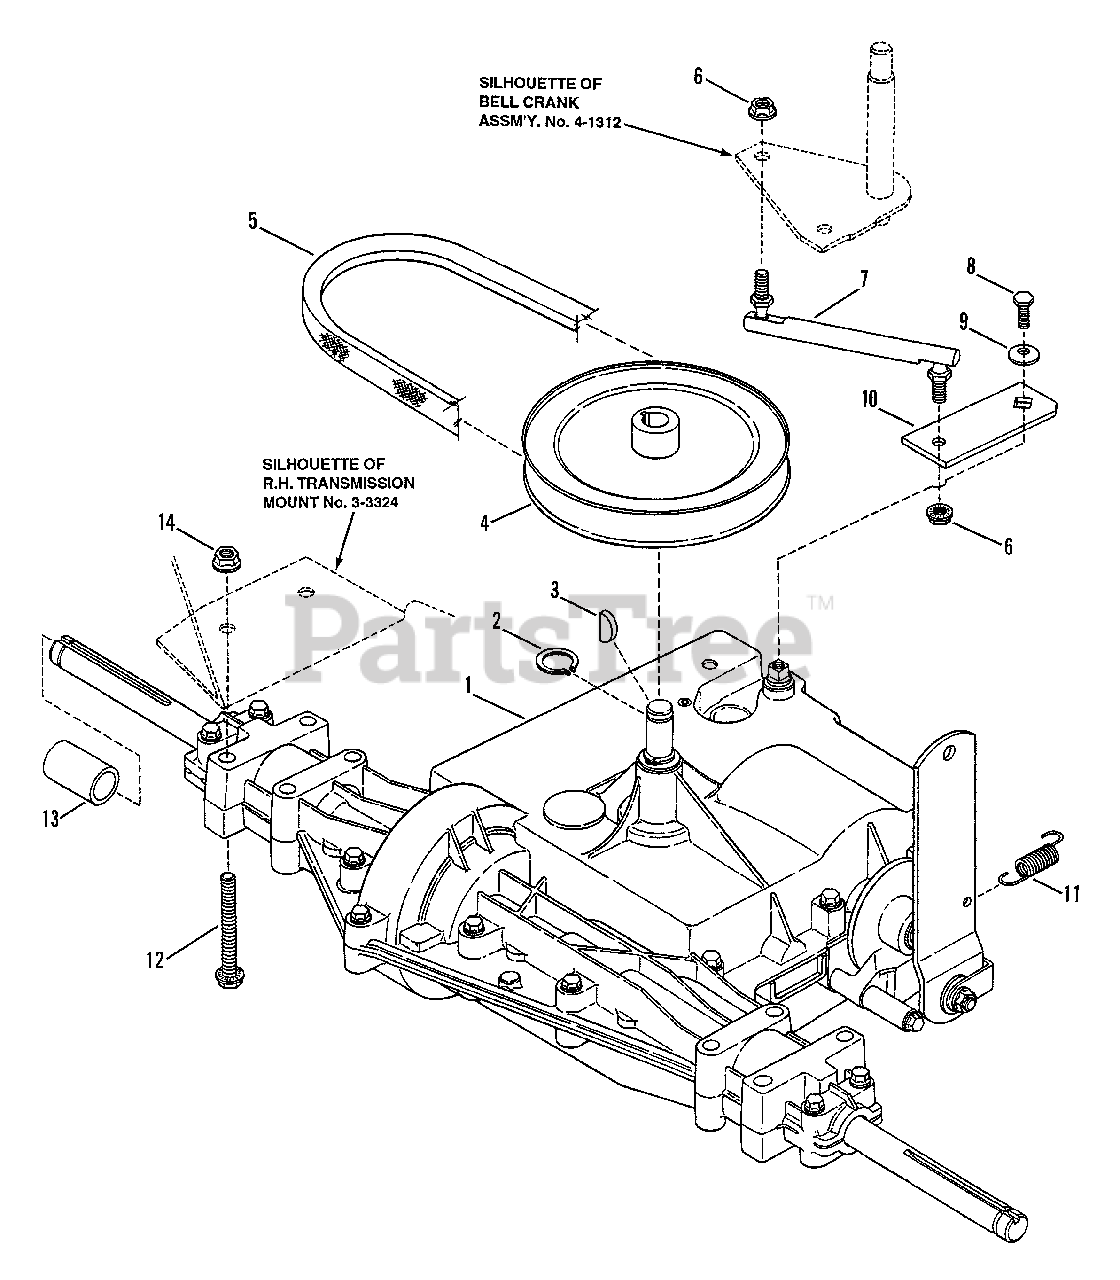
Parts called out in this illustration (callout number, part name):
1	TRANSAXLE ASSEMBLY (Peerless 930 - 6 speed)
2	RING, Retaining
3	KEY, Woodruff, 3/16 x 3/4" No. 9
4	PULLEY, Input
5	BELT, Drive HA109
6	NUT, 5/16-24 Hex Flange Lock
7	SHIFT LINK LEVER
8	BOLT, 1/4-28 x 5/8" Hex Head
9	WASHER, Bellville
10	ARM, Shift Link Lever
11	SPRING, Brake Return
12	BOLT, 5/16-18 x 2 1/4" Hex Flange Lock
13	SPACER, Wheel
14	NUT, 5/16-18 Hex Flange Lock
33324	TRANSMISSION MOUNT, R.H.
41312	BELL CRANK ASSM'Y.
